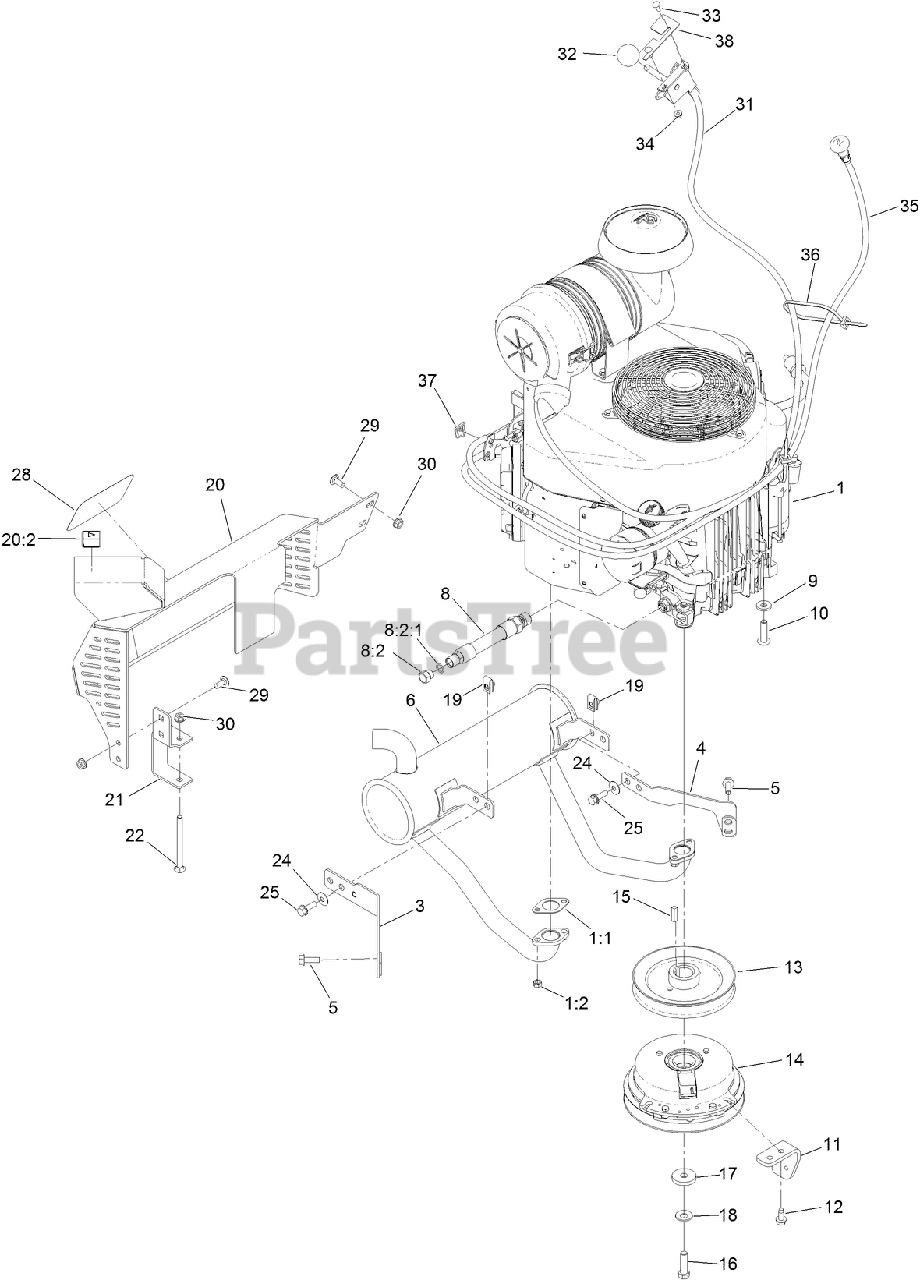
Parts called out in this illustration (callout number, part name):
1	ENGINE-KAWASAKI, FX691V
1:1	GASKET-EXHAUST
3	BRACKET-MUFFLER, FRONT
4	BRACKET-MUFFLER, REAR
5	SCREW-HHF
6	MUFFLER
8	HOSE ASM
8:2	PLUG-HH
8:2:1	O-RING
9	WASHER-BELLEVILLE
10	SCREW-BHTF
11	STOP-CLUTCH
12	SCREW-HWHTF
13	PULLEY
14	CLUTCH-200CMS
17	WASHER
18	WASHER-SPRING
19	NUT-U
20	MUFFLER GUARD ASM
20:2	DECAL-WARNING
21	BRACKET-MOUNTING, GUARD
22	SCREW-CARR
24	WASHER-BELLEVILLE
25	SCREW-HHF
28	DECAL
29	SCREW-CARR
30	NUT-HF
31	THROTTLE ASM
32	KNOB-BALL
33	BOLT-CARR
34	NUT-LOCK, FLANGE
35	CABLE-CHOKE
36	TIE-CABLE
37	CLAMP-CABLE
38	PLATE-SET, THROTTLE
